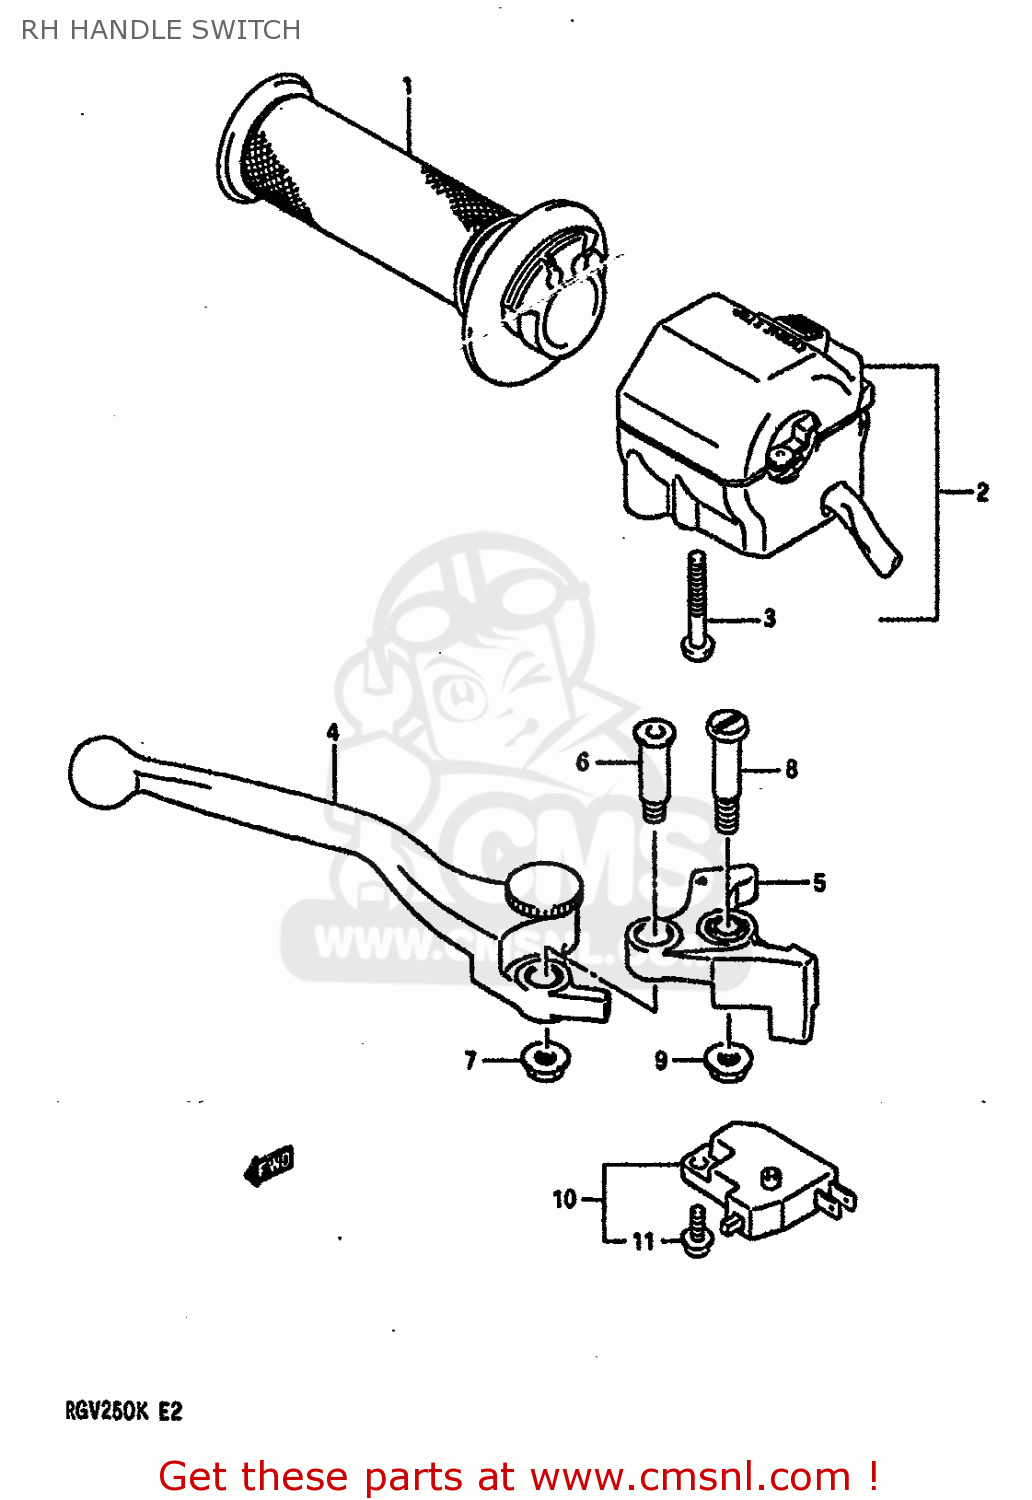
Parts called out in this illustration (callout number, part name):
1	GRIP,THROTTLE
2	SWITCH ASSY,HANDLE RH
3	SCREW, 5X45
4	LEVER,ADJUST
5	KNOCKER
6	BOLT,LEVER
7	NUT
8	BOLT,LEVER PIVOT
9	NUT 6MM
10	SWITCH ASSEMBLY,STOP
11	SCREW
